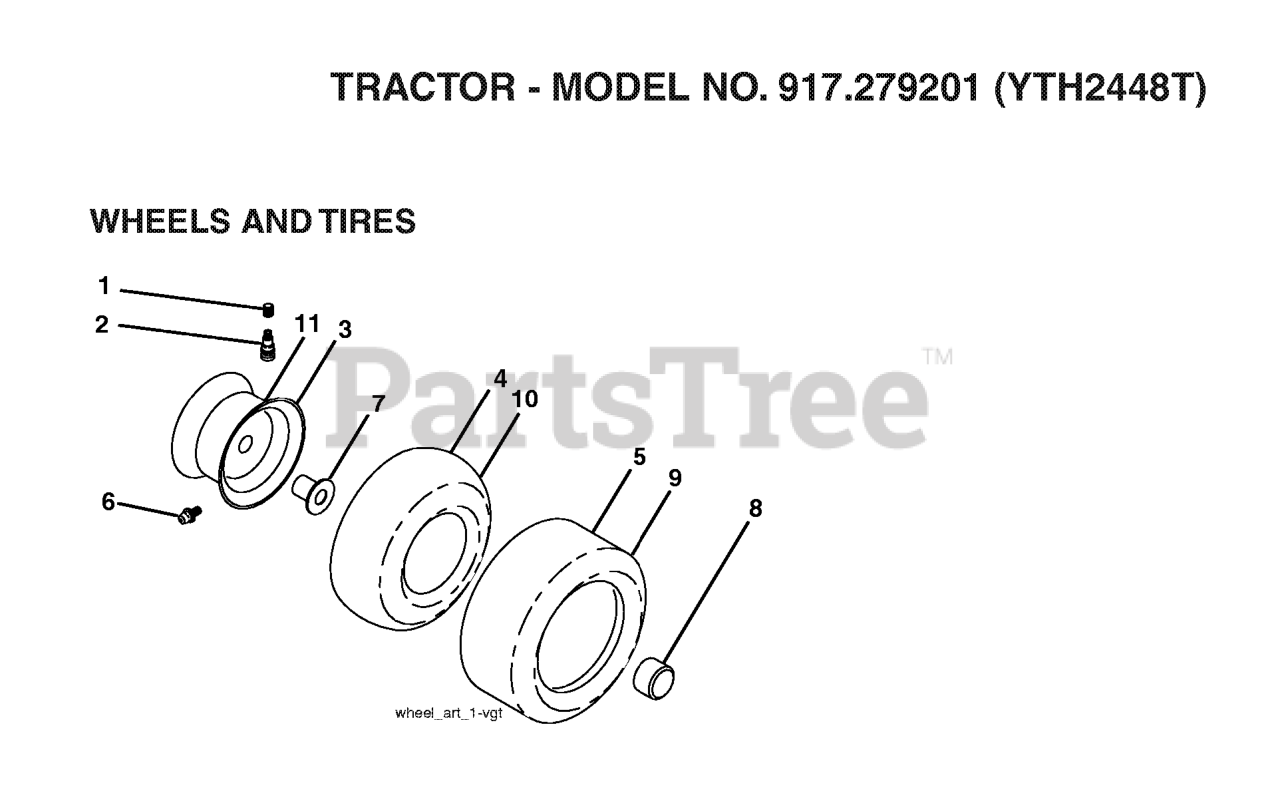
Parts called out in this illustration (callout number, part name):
2	VALVE STEM LT
3	RIM ASM 6" FRONT SILVER
4	TUBE.16X6.5/7.5-8
5	TIRE HEAVY DUTY
6	FITTING LT.
7	BEARING.FLANGE
8	CAP, AXLE BLK
9	TIRE.20X8-8.TURF.SAVER
10	TUBE.23X9.5-12
11	RIM ASM 8" REAR SILVER
